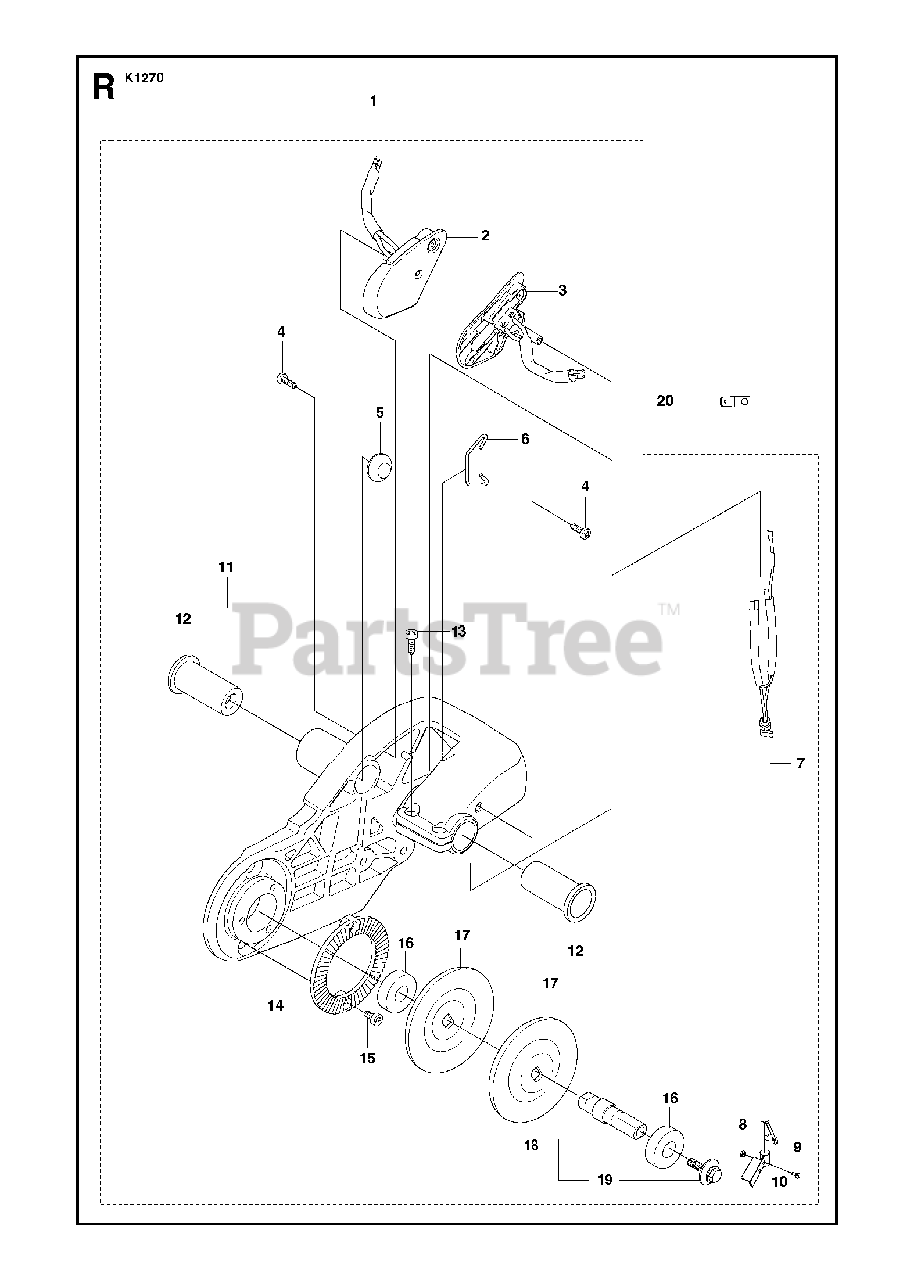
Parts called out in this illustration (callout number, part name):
1	BEARING HOUSING ASSY"14"" Rail Stop Switch,"
2	STOP SWITCHRH
3	STOP SWITCHLH
4	SCREW CRPANT
5	SPACING BLOCK
8	HEXAGON LOCKING NUT
9	SCREW CRPANM
11	BEARING HOUSING ASSY"14"" Rail, "
11	BEARING HOUSING ASSY"16"" Rail, "
11	BEARING HOUSING ASSY"16"" Rail USA, "
13	SCREW IHSCFM
15	SCREW ITXSCM
16	BALL BEARING
17	FLANGE WASHERIncl. 18
